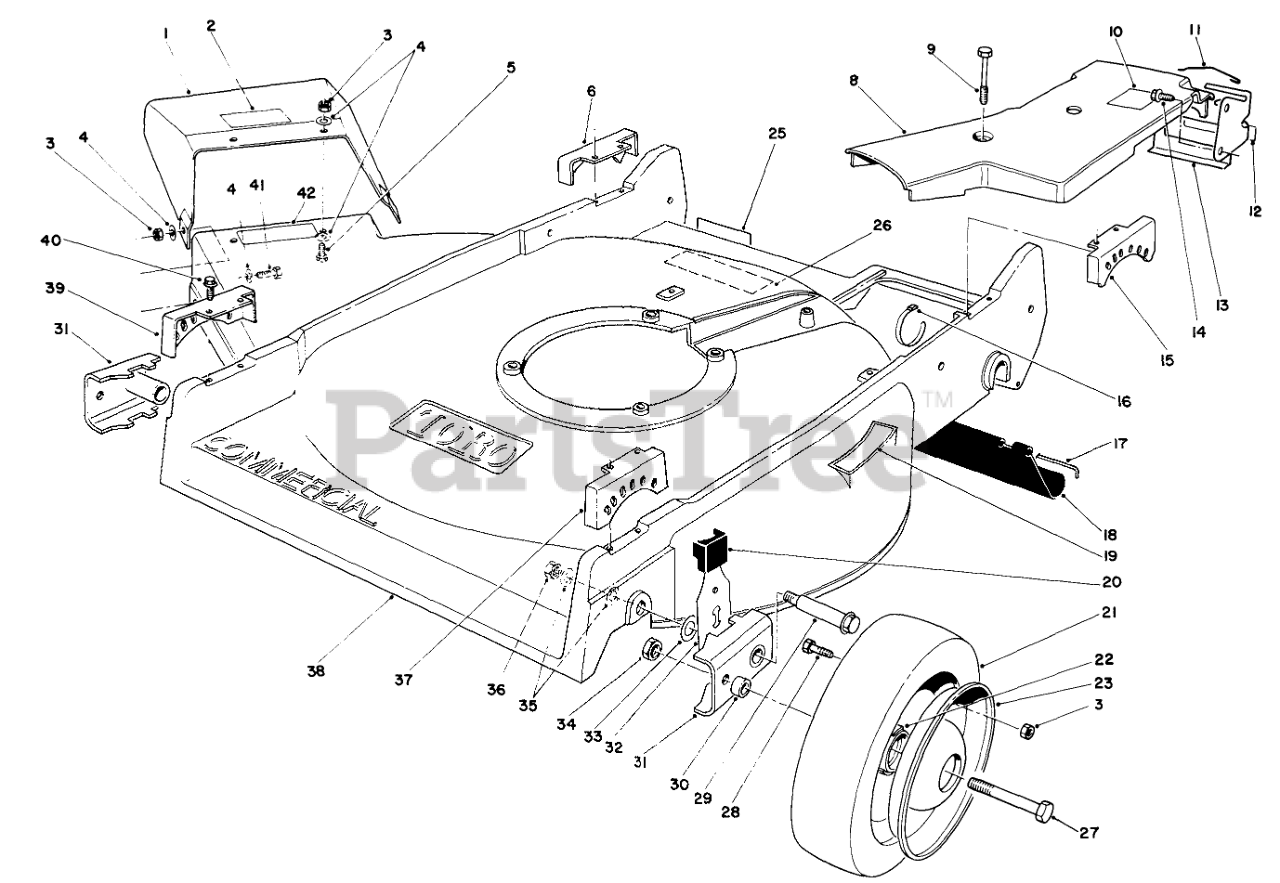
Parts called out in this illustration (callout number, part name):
1	Assembly-Deflector (Incl. Ref. #2)
2	DECAL - DANGER
3	NUT-LOCK, NI
4	WASHER-FLAT
5	SCREW-HH
6	QUADRANT-REAR, RH
8	COVER-BELT
9	SCREW-HHFTF
10	Label-Grease
11	RETAINER-CABLE
12	DECAL-POSITION, GEAR
13	BRACKET-ADJUSTMENT, TRACTION
14	SCREW-HWHTF
15	QUADRANT-REAR, LH
16	TIE-CABLE
17	ROD-SHIELD
18	SHIELD-TRAILING
19	DECAL - STEP PAD INT'L
20	KNOB-ARM
22	Hub Ass-y
23	Wheel-Half
25	DECAL FRENCH REGUL.
26	DECAL - DIN/DANGER
27	SCREW-HH
28	SCREW-HH
29	WHEEL BOLT
30	SPACER-WHEEL
31	ARM-PIVOT, FRONT
32	FRONT SPRING ARM ASM
33	WASHER-THRUST
34	NUT-LOCK, CONE
35	WASHER
36	Nut
37	QUADRANT-FRONT, LH
38	Housing-Commercial (Incl. Ref. #19, 26 & 42)
39	QUADRANT-FRONT, RH
40	SCREW-HWHTF
41	SCREW-HH
42	DECAL - WARNING/INT'L
